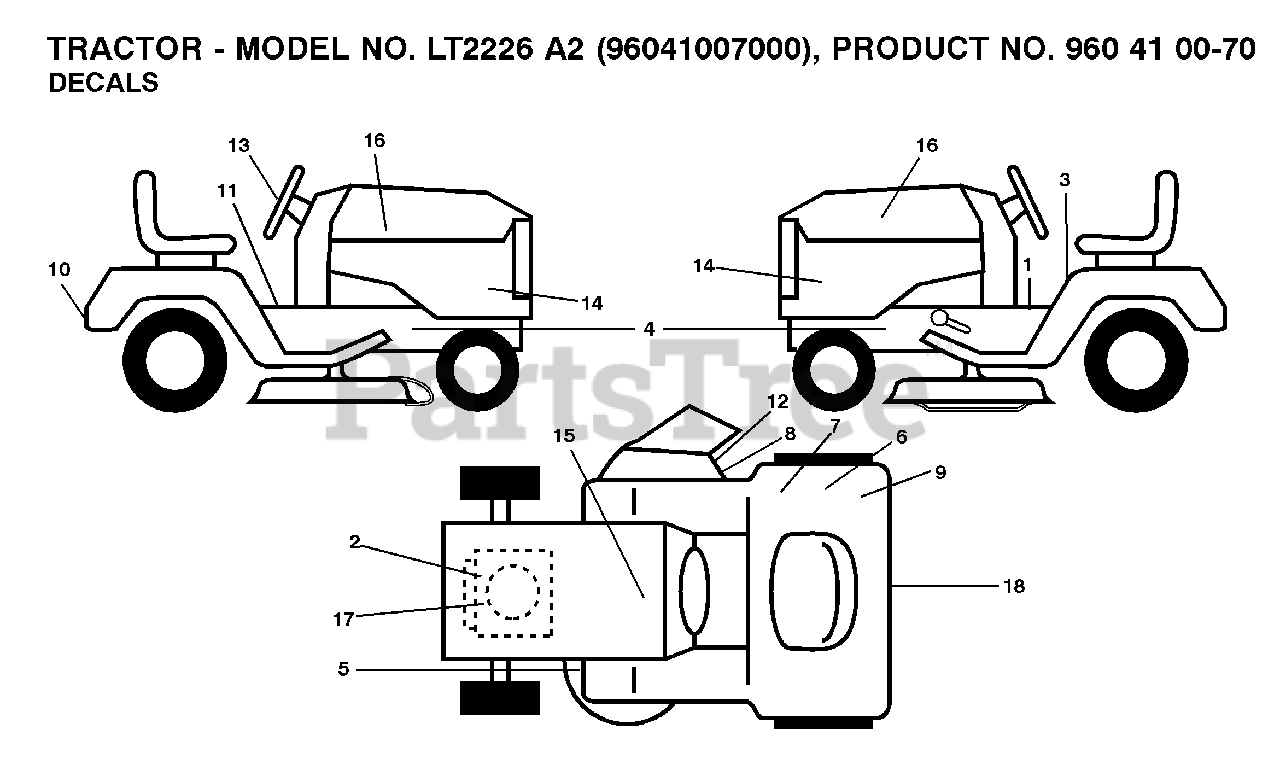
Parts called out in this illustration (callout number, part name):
1	DECAL PARK BRAKE
5	DECAL V BELT SCHEMATIC
7	DECAL.80 DBA.AUSTRALIA
8	DECAL, DEFLECT WARNING
12	DECAL.INTERNATIONL.CUTFINGER
15	DECAL BTRY SYMBOLS
